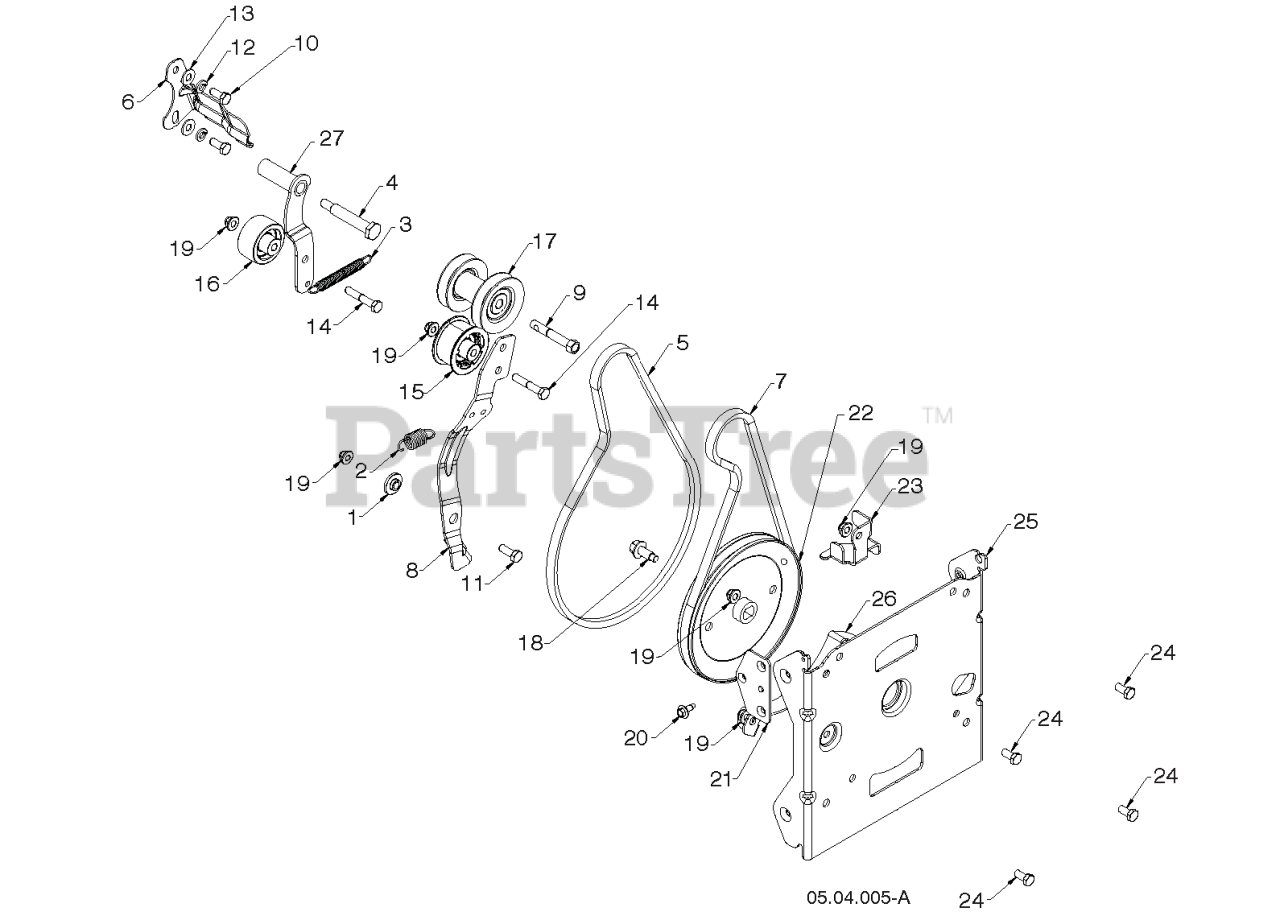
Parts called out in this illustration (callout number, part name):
1	BUSHING.BRAKE.ARM
2	SPRING RETURN, IDLER ARM, IMPE
3	SPRING RETURN IDLER ARM
4	BOLT 5/16-24X2.25 HEX HEAD SHO
5	BELT.DRIVE.SNOW.DUAL
6	BELT KEEPER BRACKET
7	LOW CRANK IMPELLER BELT
8	ARM.IDLER.AUTO-PH.676
9	BOLT.ENGINE.PULLEY
10	SCREW 5/16-24 X .75 GR5
11	BOLT HEXAGON BOLT 5/16-18 X 7/
12	NUTNYLOK.FLRANGE.5/16-18
13	WASHER 11/32 X 11/16 X 14 GA T
14	BOLT, HEX 5/16-18X1-3/4
15	PULLEYIDLER.2.0.W/SPACER.CZ
16	PULLEY.IDLER.FLNGLESS.W/SPACER
17	PULLEY.ASM.IMPELLER/DRIVE
18	SCREW HEXAGON HEAD FLANGE 3/8-
19	NUTNYLOK.FLRANGE.5/16-18
20	HEX.WASHER.HEAD 1/4-20 X .65
21	BRACKET NUT BLACK ZINC PLATE
22	PULLEY IMPELLER DD 4L
23	GUIDE.LOWER.AUGER.BELT.479
24	BOLT, HEX HEAD 5/16-18
25	BRACKET.AUG.HOUSING.INTER.BLAC
26	BRACKET.BELT.KEEPER.LOWER.BLAC
27	ARM IDLER DRIVE WELDMENT_HOT
